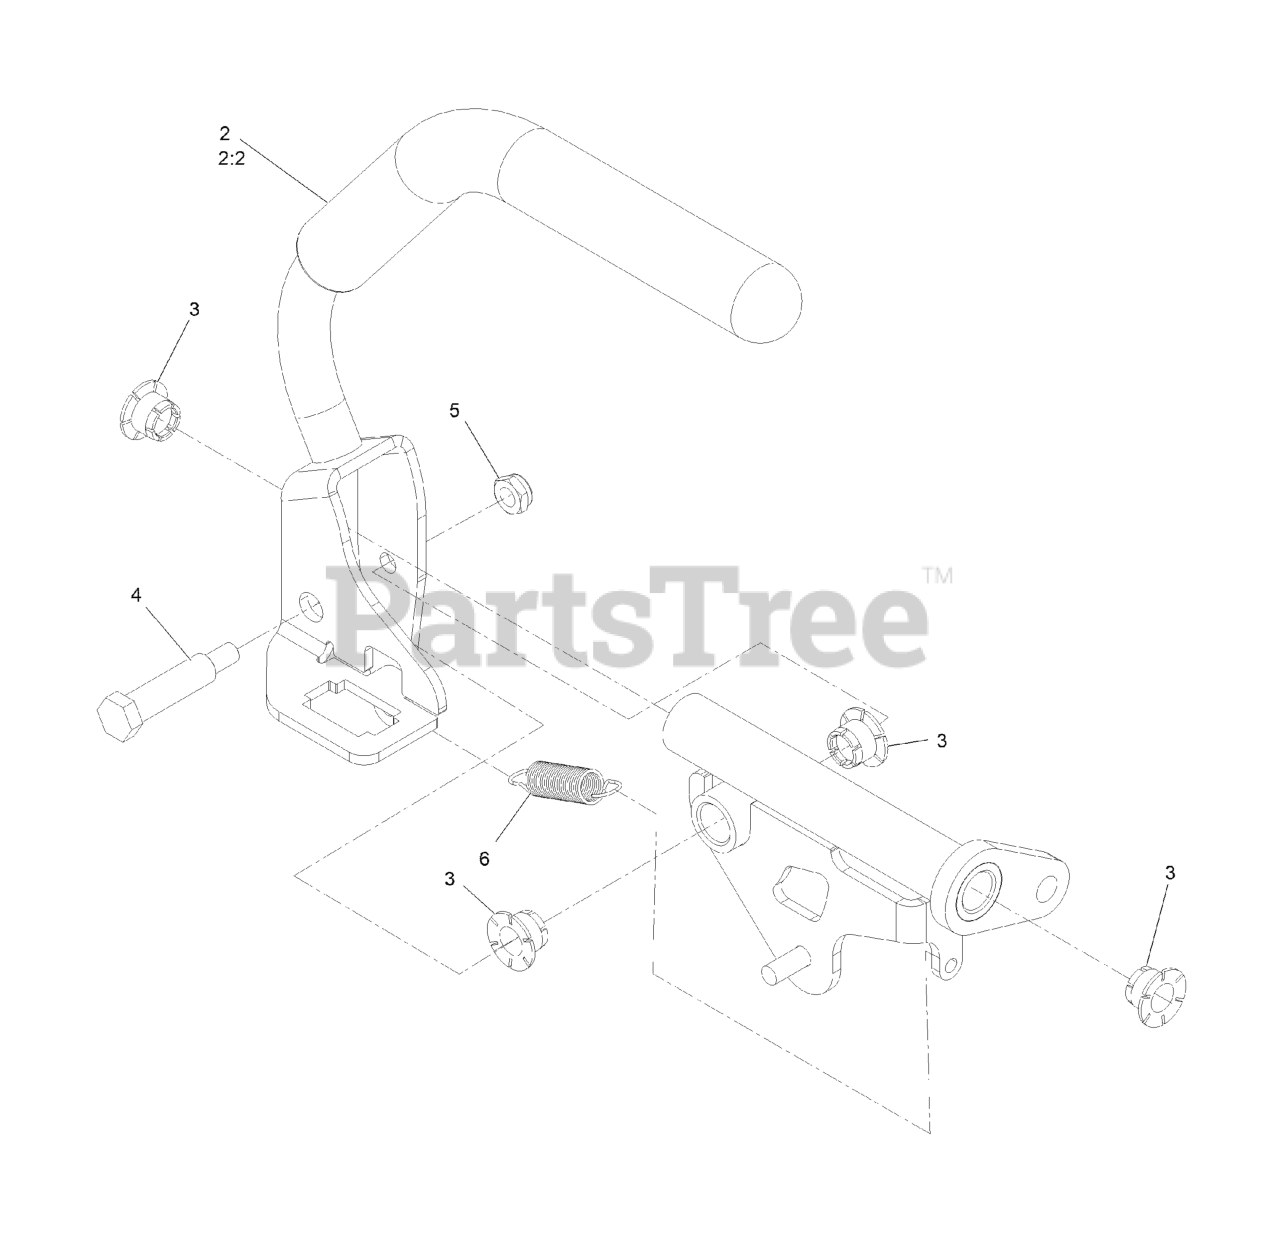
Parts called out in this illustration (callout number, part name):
2	ASM, RT CONTROL LEVER W/ GRIP
2:2	GRIP, DRIVE LEVER
3	BEARING, IGUS
4	BOLT-SHOULDER
5	NUT-LOCK, NI
6	SPRING-EXTENSION
